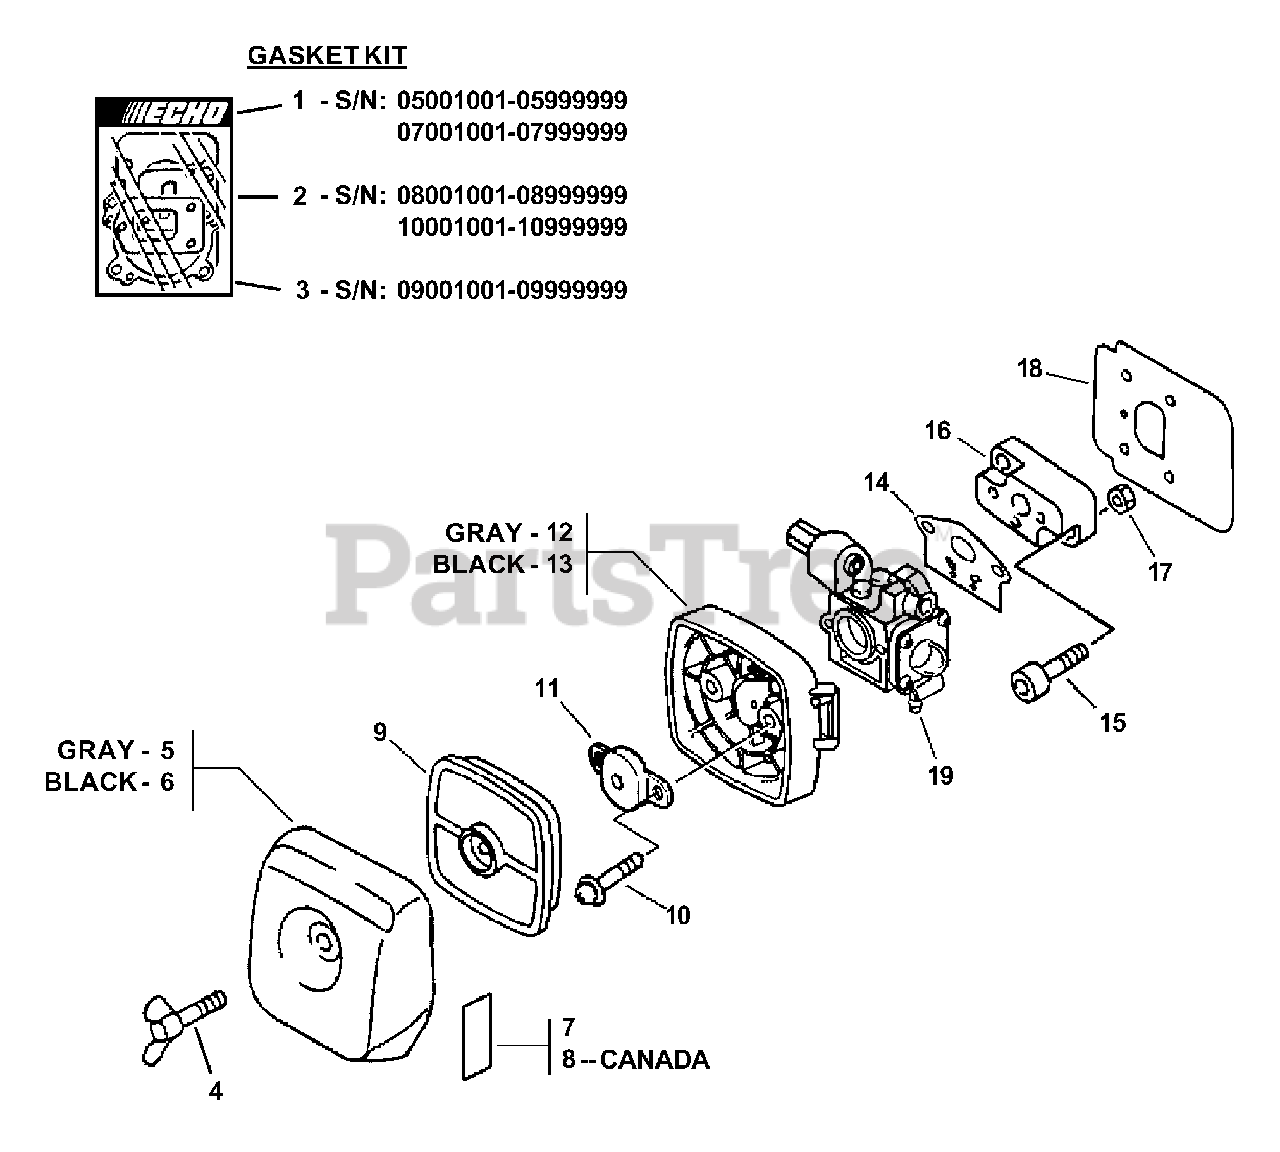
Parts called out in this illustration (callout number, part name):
1	GASKET KIT
2	GASKET KIT
3	GASKET KIT
4	THUMBSCREW
5	COVER, AIR FILTER - GRAY
6	COVER, AIR FILTER - BLACK
7	LABEL - CHOKE
8	LABEL - CHOKE
9	FILTER, AIR - SINGLE LAYER
10	SCREW - 5X65
11	PLATE, PREVENT
12	CASE, AIR FILTER - GRAY
13	CASE, AIR FILTER - BLACK
14	GASKET, INTAKE
15	SCREW - 5X20
16	INSULATOR, INTAKE
18	SHIELD, INTAKE
19	CARBURETOR
